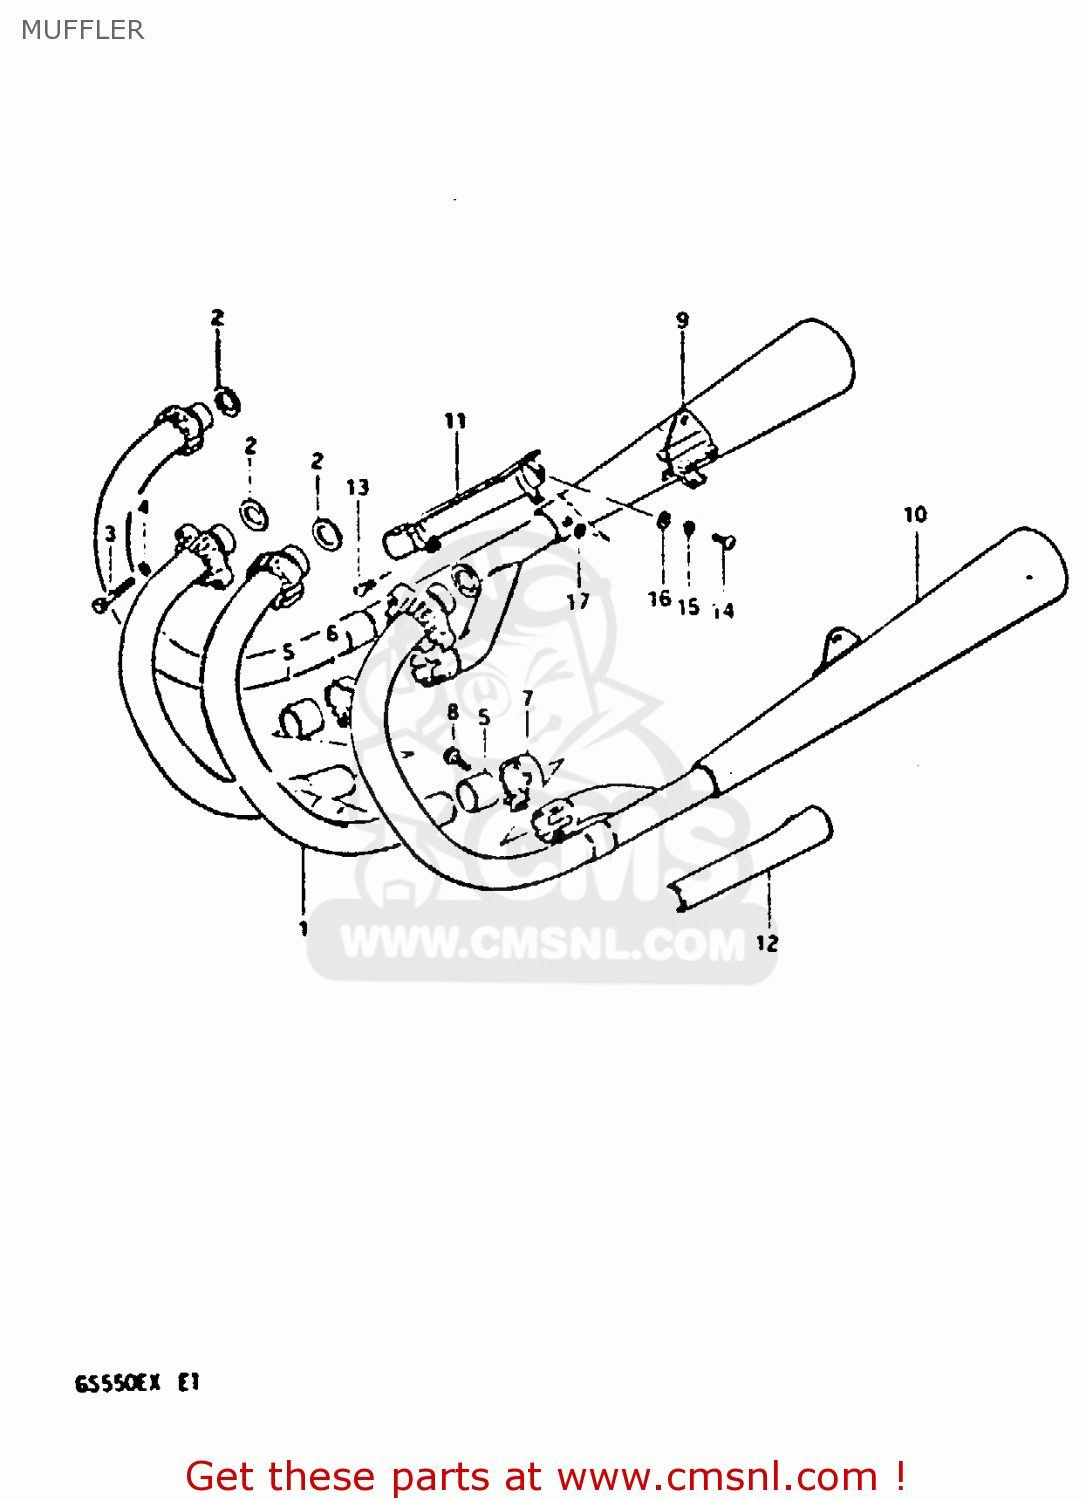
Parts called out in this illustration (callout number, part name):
1	PIPE,EXHAUST,CENTER
2	GASKET,EXHAUST PIPE (NAS)
3	BOLT
4	LOCK WASHER
5	CONNECTOR,MUFFLER
6	CLAMP,MUFFLER CONNECTOR,R
7	CLAMP,MUFFLER CONNECTOR,L
8	BOLT
9	MUFFLER ASSEMBLY
10	MUFFLER ASSEMBLY
11	COVER,MUFFLER
12	COVER,MUFFLER
13	SCREW
14	SCREW 6X12
15	LOCK WASHER
16	WASHER
17	GASKET 6.2X12X1.5 (MCA)
